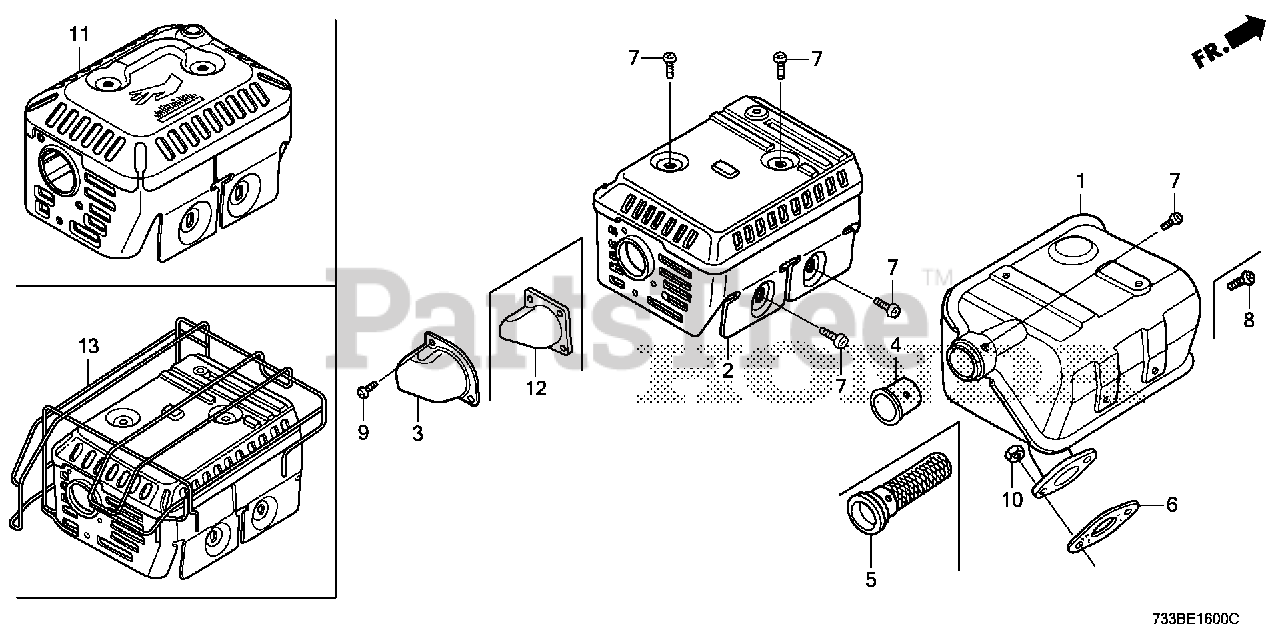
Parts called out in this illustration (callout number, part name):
1	MUFFLER (ARRESTER)
1	MUFFLER
3	DEFLECTOR, MUFFLER
4	PIPE, TAIL
5	ARRESTER, SPARK
6	GASKET, MUFFLER
6	GASKET, MUFFLER (NINGBO SIL GASKET)
7	SCREW, TAPPING (5X8)
8	SCREW, TAPPING (4X6)
9	SCREW, TAPPING (4X6)
10	NUT, HEX. (8MM)
12	GUIDE, MUFFLER
13	PROTECTOR (UPPER)
